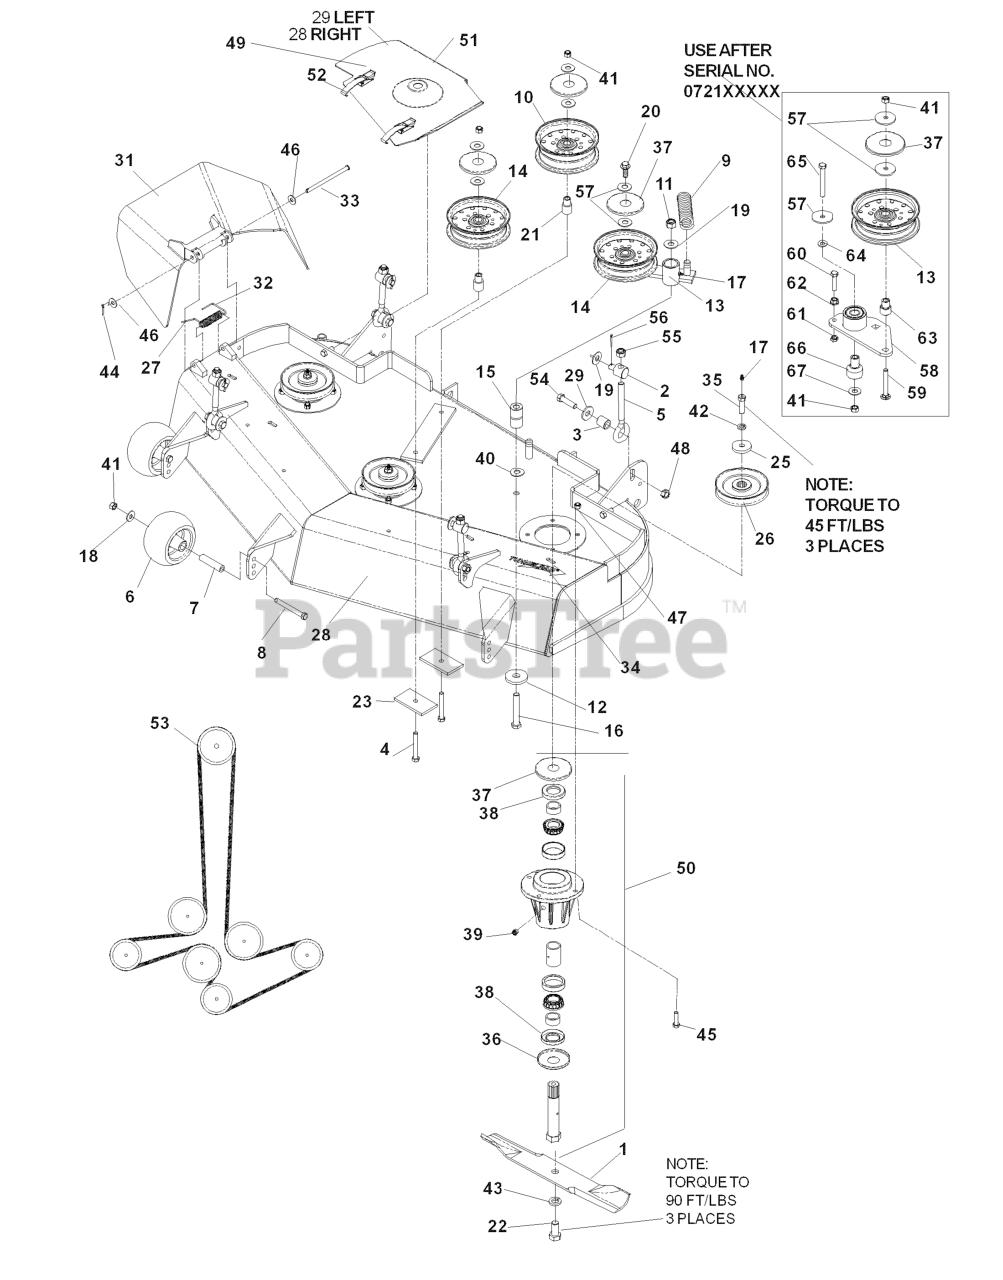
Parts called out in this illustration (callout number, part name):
1	BLADE OEM 16 1/4"
4	SCREW 3/8C X 2 3/4 HEX CAP
6	ANTI-SCALP ROLLER
8	HCS 3/8C X 3 1/2
10	IDLER PULLEY (TALL)
11	NUT 1/2-13 HEX NYLOC ZD
12	WASHER, SUPPORT
14	IDLER PULLEY
15	PIVOT BUSHING
16	HCS 1/2C X 3 1/4
17	ZERK
18	WASHER 3/8 FLAT
19	WASHER 1/2 FLAT
20	4CS 3/8C X 1 SERRATED HEAD
21	IDLER BUSHING
22	HCS 5/8F X 1 1/4
23	SUPPORT PLATE
24	SPRING WASHER - .50
25	SPINDLE WASHER
26	RP PULLEY - 42/48"
27	CAP-SLEEVE
28	DECK W/DECALS 48" HUS
29	48 BELT SHIELD ASM - RH
30	48 BELT SHIELD ASM - LH
31	DISCHARGE CHUTE 48"
32	SPRING - TORSION
33	PIN-CLEVIS 5/16 DIA X 5.19 ZD
34	DECAL, TUNNEL RAM 6"
35	HCS 7/16-20 GD 8 SPEC
36	BOTTOM DUST CAP
37	TOP DUST CAP
38	SHAFT SEAL
39	PLUG-VENTED
40	WASHER 1/2 X 1.44 HRD ZD
41	NUT 3/8-16 NYLOC
42	WASHER 7/16 LOCK
43	LOCKWASHER 5/8
44	RP_COTTER PIN 1/8 X 3/4
45	HCS 5/16C X 1 1/4
46	WASHER 5/16 FLAT
47	NUT 5/16 NYLOC
48	NUT 7/16C CENTERLOCK
49	DECAL, EURO SEVERING
50	HSG KIT 52/61 RIBBED
51	RIVET, BLIND, 5/32 DIA
52	DRAW LATCH
53	BELT, DECK 48"
54	HCS 7/16 - 14 X 1 3/4
55	NUT 1/2-13 HEX NYLOC ZD
56	PIN COTTER 1/8 X 1 ZD
57	WASHER, 3/8, SPEC
58	ARM-IDLER W/BRG
59	RHSNB 3/8-16 X 2.75
60	HCS 3/8-16 X 1-1/2
61	NUT 3/8-16 HEX JAM
62	NUT 3/8C WHIZ
63	BUSHING, IDLER
64	WASHER 3/8 SAE FLAT
65	HCS 3/8C X 3
66	PIVOT, BEARING
67	WASHER 3/8 FLAT
